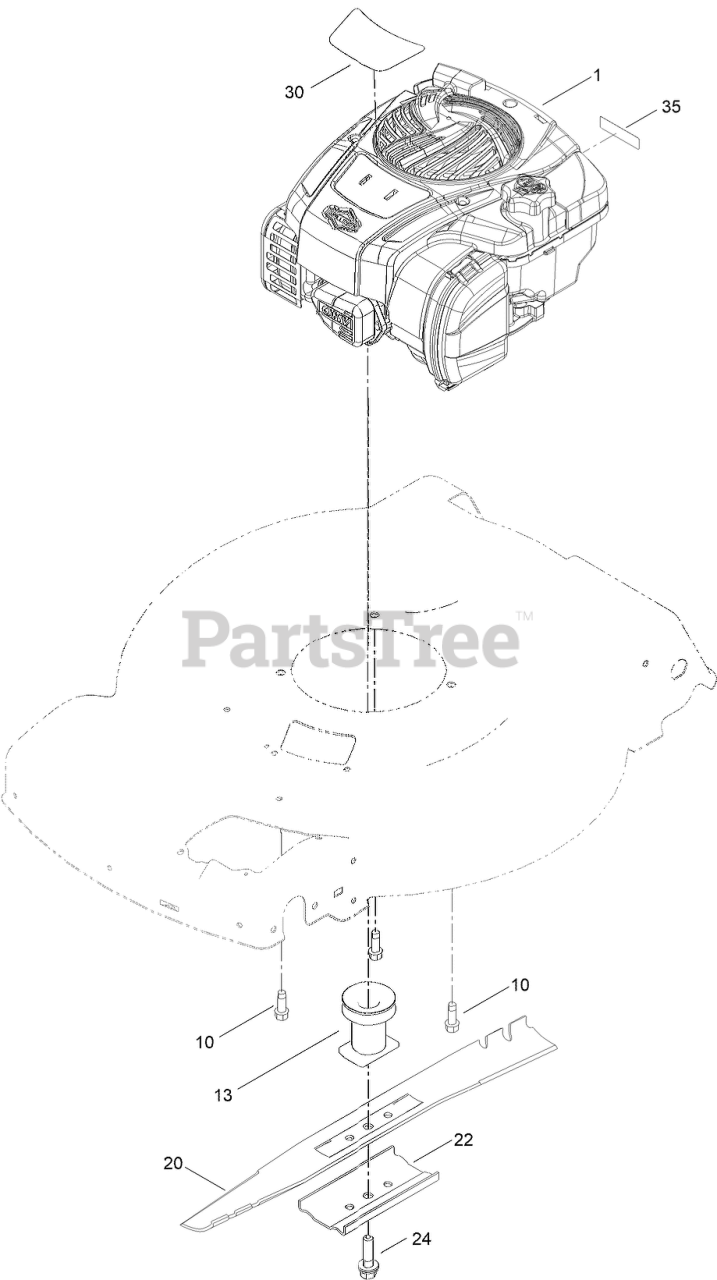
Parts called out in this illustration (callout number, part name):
1	ENGINE-BRIGGS, 625 EXI ZS
10	SCREW-TAPTITE
13	DRIVER-BLADE
20	BLADE-22 INCH
22	SUPPORT-BLADE
24	BOLT-BLADE
30	DECAL-BRIGGS 625 EX
35	DECAL-ARRESTOR, SPARK
